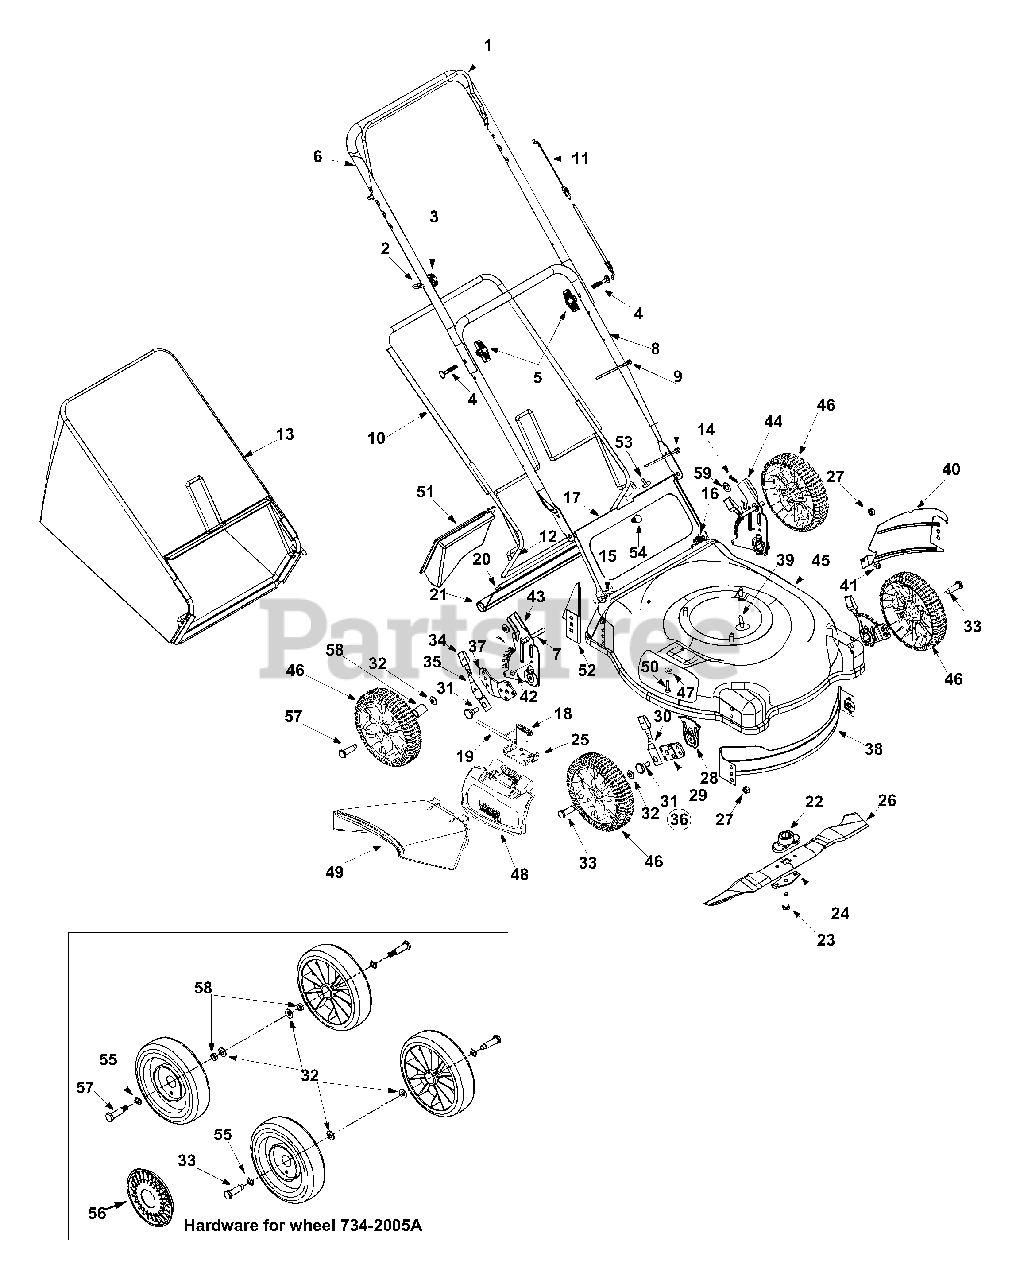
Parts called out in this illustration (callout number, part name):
2	Rope Guide
3	Handle Knob 1/4-20 Thd.
4	Curved Hd. Bolt 5/16-18 x 2"
5	Hand Knob
7	Weld Pin
9	Cable Tie
11	Control Cable - 53"
14	Int. Cotter Pin 5/16" Dia.
15	Door Spring - R.H.
16	Door Spring - L.H.
19	Hinge Pin
20	Wire Rod
21	Rear Flap
22	Blade Adapter w/Star
23	Hex Bolt 3/8-24 x 1.5" Lg.
24	Blade Bell Support
26	21" Mulching Blade w/Star
27	Flange Nut 3/8-16 Thd.
28	Height Adj. Plate
30	Front Spring Lever
31	Shld. Bolt .5" Dia. x .357"
32	Bell Washer .38" I.D. x .88" O.D.
33	Front Axle Bolt
34	Spring Lever Knob
35	Rear Spring Lever
36	Height Adj. Assy. Comp. - RH
37	Pivot Bar R.H.
41	Torx Mach AB-Tap Scr. 1/4 x.62"
42	Hex Ind Wash. Scr. 1/4-14:.625
43	Handle Brkt. Ass'y.-RH
44	Handle Brkt. Ass'y.-LH
45	Deck 21"
46	Wheel Complete
47	Bell Washer 1/4" I.D.
48	Hinged Mulching Plug
49	Chute Deflector: Side Discharge
50	Hex Hd Self-Tp Scr. 1/4-20 x .5"
51	Mulching Baffle Plug
53	Truss Scr. #10-24 x .38" Lg.
55	Wave Washer
56	Hub-Cap- Rad. Spoke- Yellow
57	Rear Axle Bolt
58	Spacer
59	Washer
